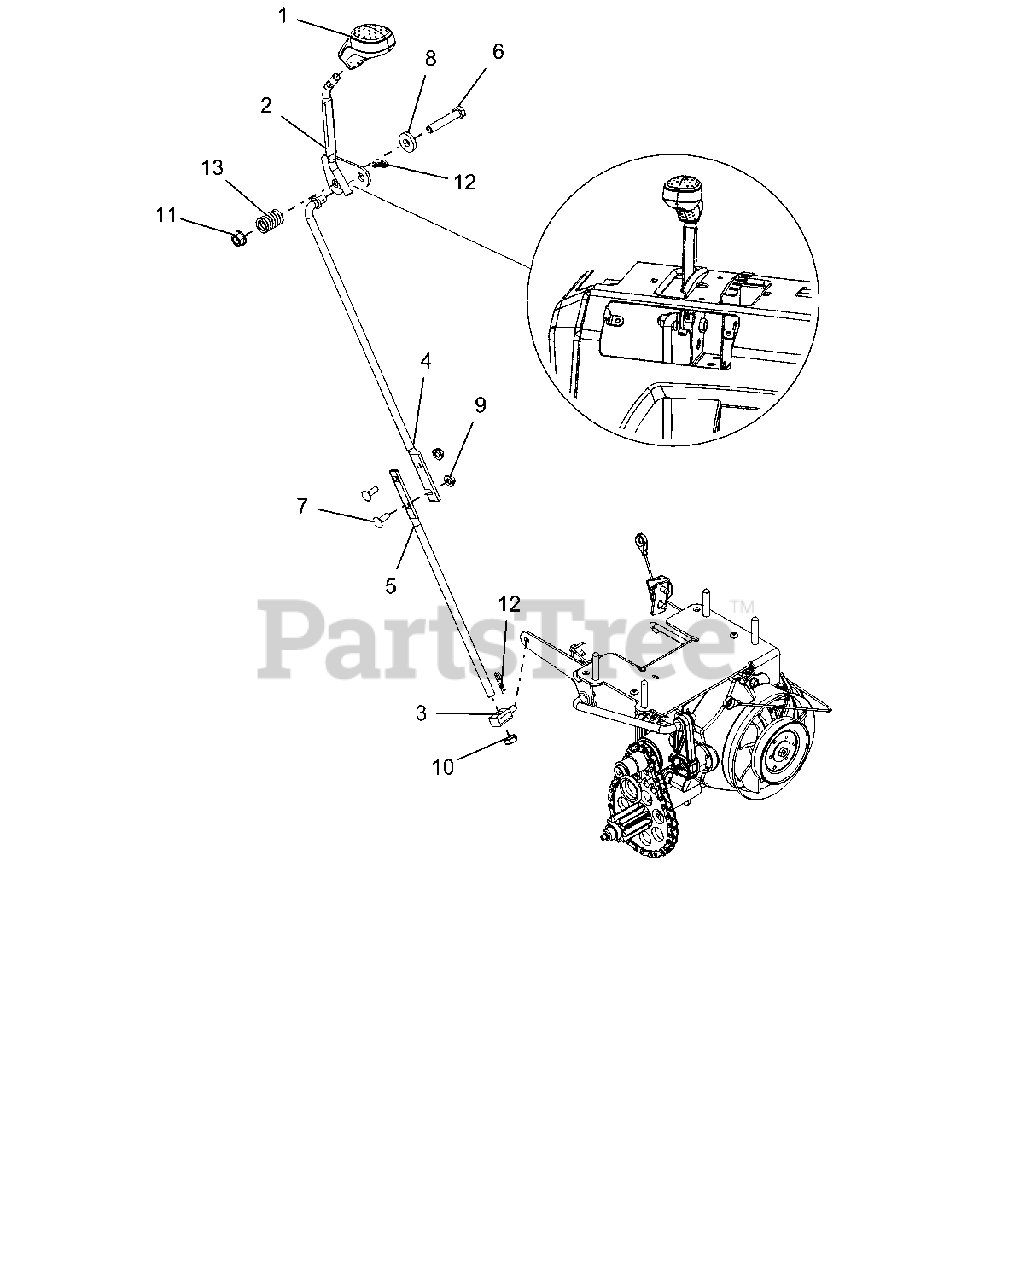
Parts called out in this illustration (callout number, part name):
1	KNOB, CONTROL, DASH
2	WELDMENT,LG DASH SPEED CONTROL
3	PIVOT,SHIFT ROD .375-16(TRUNN)
4	ROD, SHIFT - UPPER
5	ROD. HYDRO SHIFT - LOWER
6	@BLT-HEX .38-16X2.00 GR5 YWZC
7	@BLT-RDHDSQNK .25-20X.75 G5YZ
8	WSHR-FL-STL .406X1.00X.188 YWZ
9	@NUT-LK-CTR-FLG .25-20 YWZC
10	NUT-HEX-JAM .375-16 YWZC
11	@NUT-LK-TOP-FLG .38-16 YWZC
12	PIN-HAIR INT .08X.18X1.18 YWZC
13	SG-COMP .125X.781X1.250
